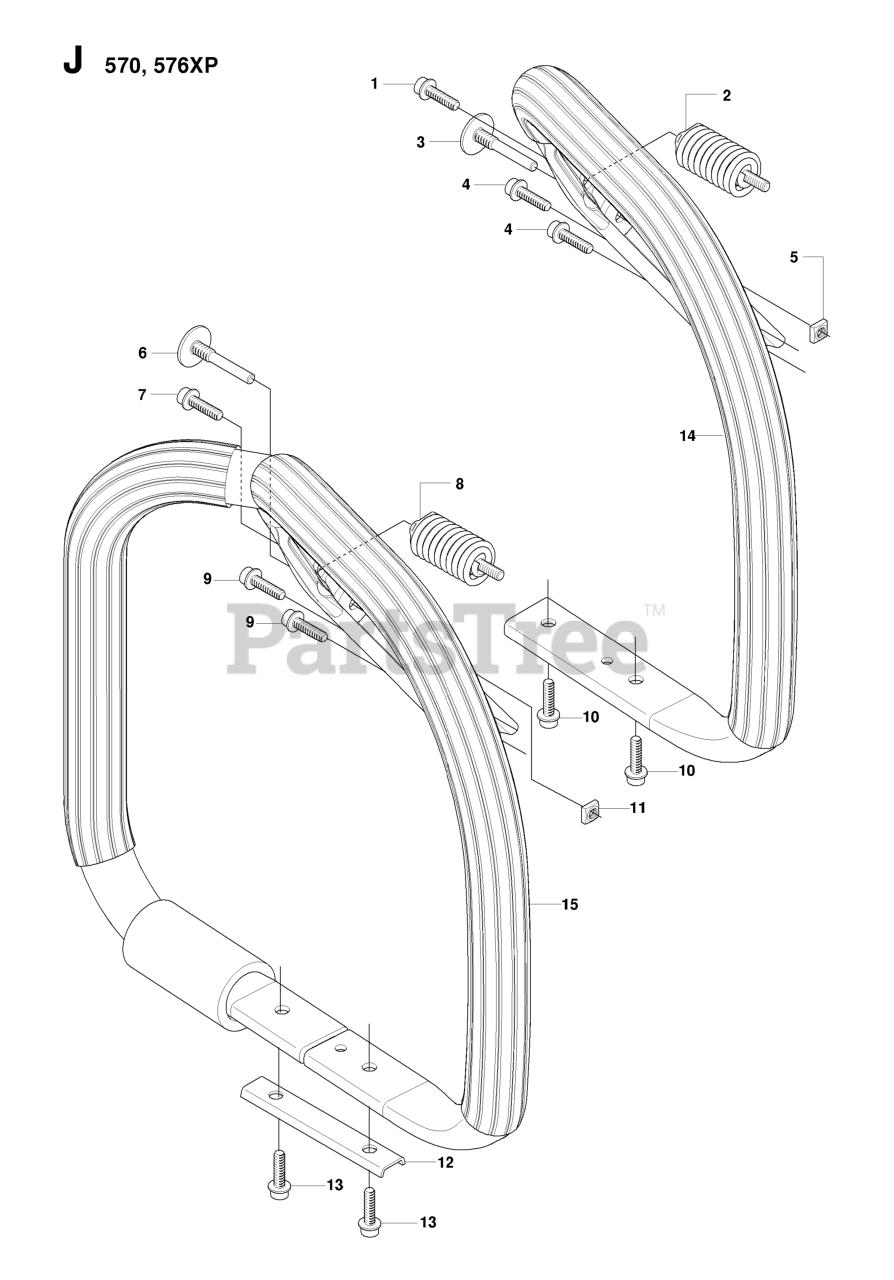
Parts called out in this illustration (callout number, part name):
2	ANTIVIBE MOUNT
8	ANTIVIBE MOUNT
14	FRONT HANDLE ASSY
14	%FRONT HANDLE
